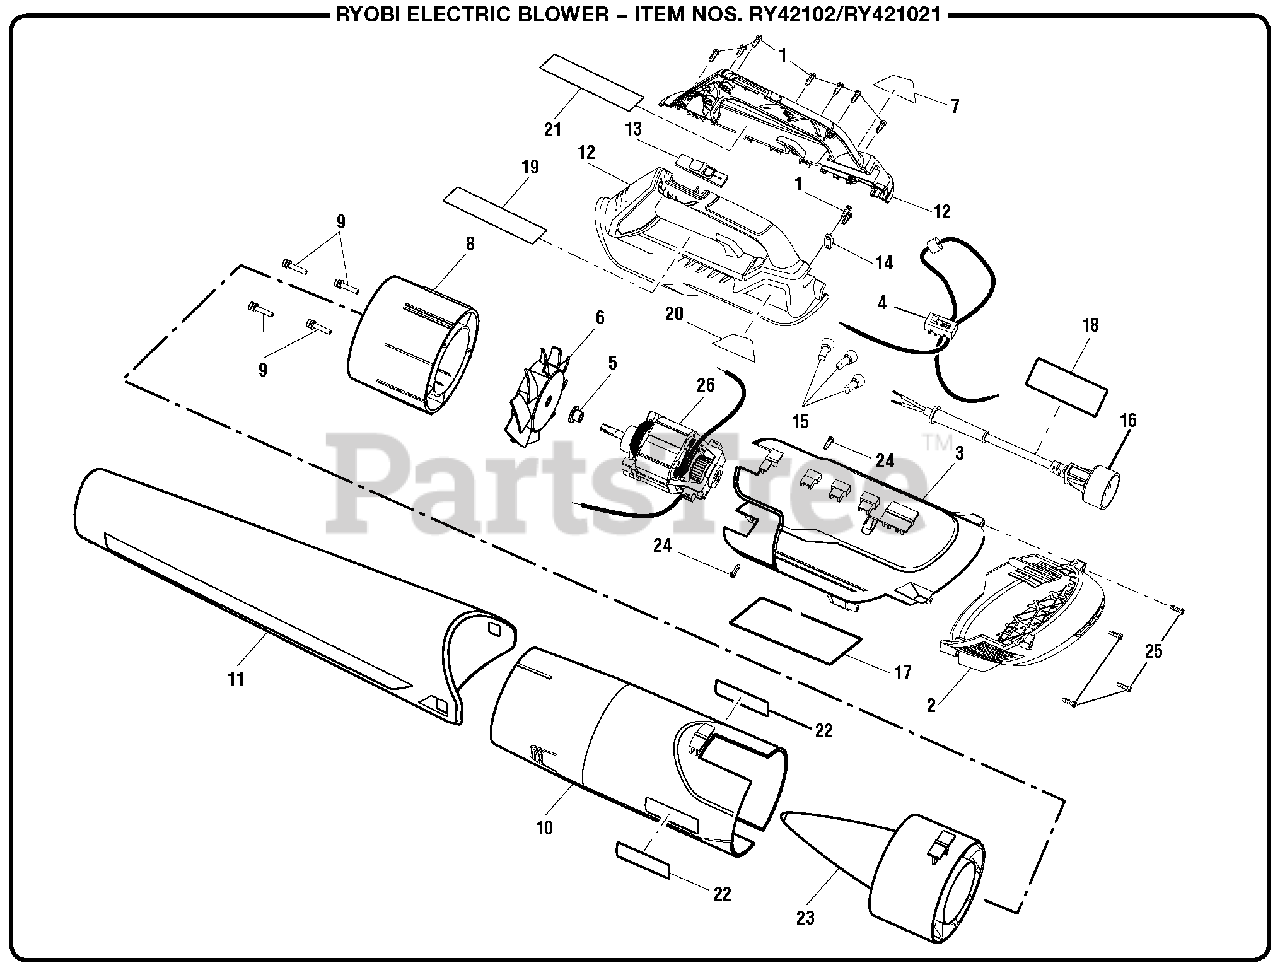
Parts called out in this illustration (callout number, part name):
1	Screw (M4 x 14 mm, T15 Torx Pan Hd.)
2	Inlet Guard
3	Housing Assembly
4	Switch and Fuse Assembly
6	Fan w/Insert Nut
7	8 Amp Label (Right)
8	Motor Housing Assembly
9	Screw w/Washers (M5 x 25 mm, T25 Torx Cap Hd.)
10	Outlet Housing Assembly
11	Blower Tube
12	Handle Assembly
13	Switch Trigger
14	Cord Clamp
15	Wire Connector
16	Power Cord Assembly
17	Data Label (RY42102)
18	Warning Label (Fr/Sp)
19	Icon Warning Label
20	8 Amp Label (Left)
21	Warning Label
22	Logo Label
23	Tail Cone
24	Screw (M4 x 16 mm, T15 Torx Pan Hd.)
25	Screw (M4 x 20 mm, T20 Torx Pan Hd.)
26	Motor Assembly
